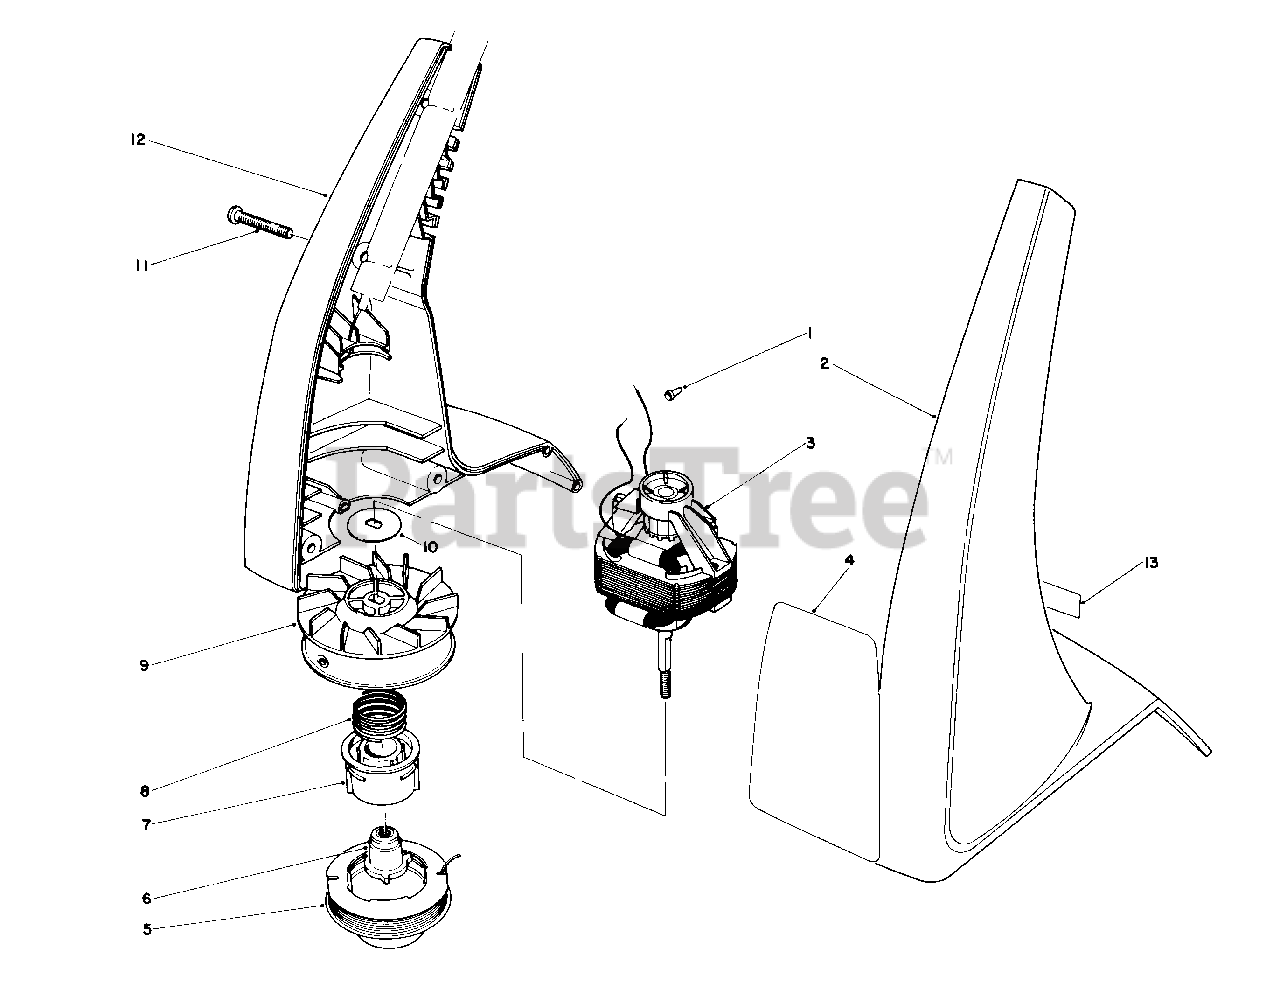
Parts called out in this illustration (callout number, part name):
1	Connector-Wire
2	Housing-L.H.
5	Cutting Line-12' .05 Dia. (Prewound on Spool)
7	Core-Spool
8	Spring
9	Drum w/Eyelet
10	Washer-Motor
11	Screw
12	Housing-Assembly R.H. (Incl. Ref. #13 & 14)
